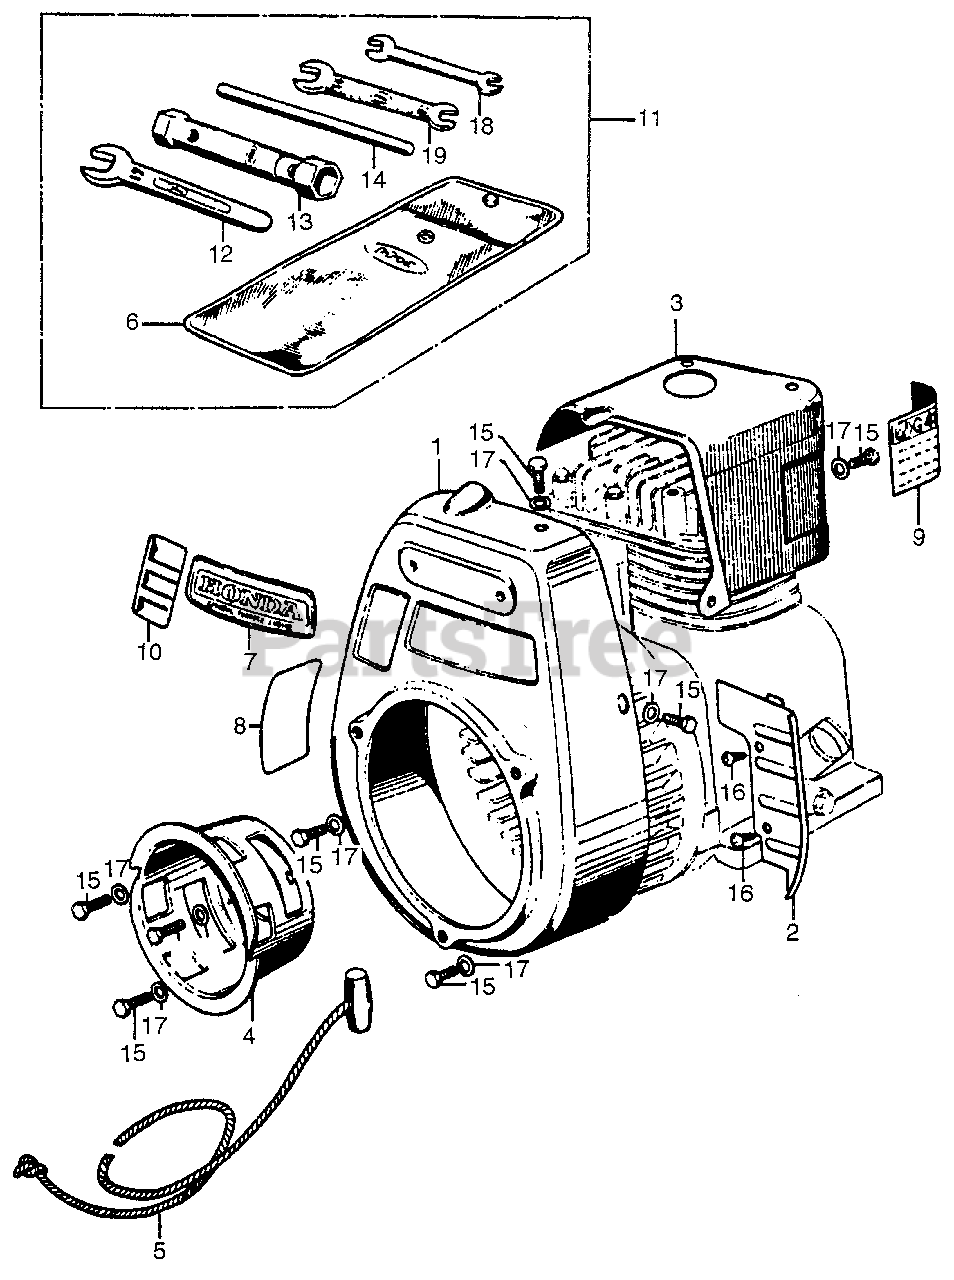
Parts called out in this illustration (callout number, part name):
1	COVER, FAN *NH31* (MCKINLEY WHITE) (NOT AVAILABLE)
2	PLATE B, WIND
3	COVER, SIDE *NH31* (MCKINLEY WHITE)
4	PULLEY, STARTER (RECOIL STARTER DISMOUNTED)
5	ROPE, STARTER (#6X64") (NOT AVAILABLE)
7	MARK, TOP (NOT AVAILABLE)
8	MARK, OIL LEVEL
9	PLATE, CAUTION
10	PLATE, THROTTLE
11	TOOL ASSY.
12	WRENCH, OPEN END (7MM)
13	WRENCH, SPARK PLUG (NOT AVAILABLE)
14	HANDLE, BOX WRENCH
15	BOLT, HEX. (6X12)
16	SCREW, TAPPING (5X10) (NOT AVAILABLE)
17	WASHER, PLAIN (6MM)
18	WRENCH (8X12) (OPEN END)
19	WRENCH (10X14) (OPEN END)
